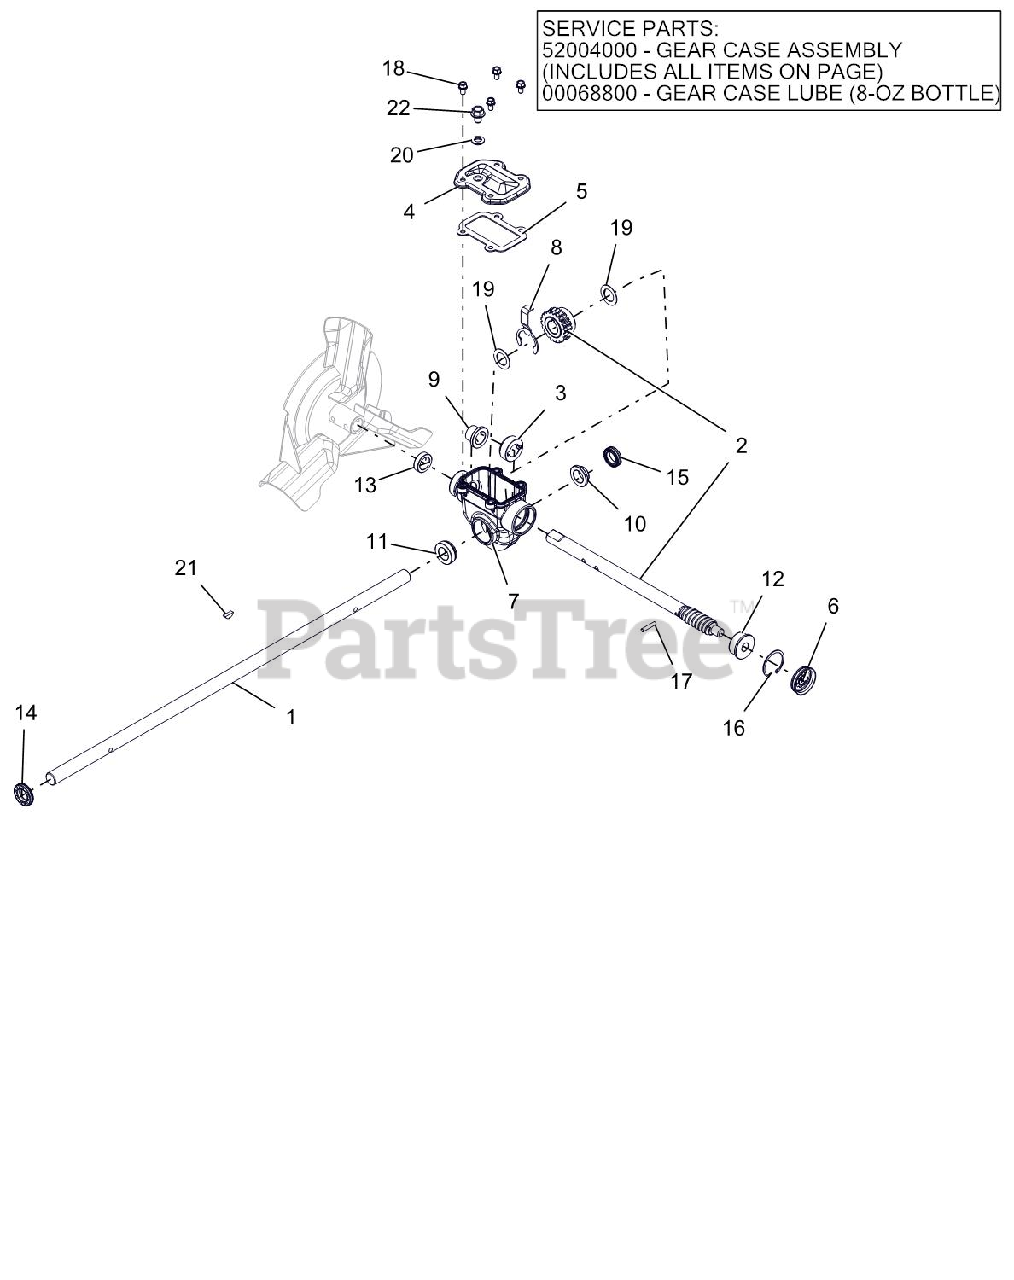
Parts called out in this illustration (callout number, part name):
1	SHAFT, RAKE-28" (.750 DIA)
2	SHAFT AND WORM GEAR ASSEMBLY
3	THRUST COLLAR, .75" ID SLIPFIT
4	COVER, TOP - COMPACT
5	GASKET, TOP - COMPACT GEARCASE
6	COVER, GEAR CASE 1.50"
7	GEARCASE, COMPACT ALUMINUM
8	BUSHING RETAINER, COMPACT
9	BSHG-FLG .755X.878X.75X1.25
10	BSHG-FLG .755X.878X.424X1.25
11	BSHG-FLG COMPACT, RIGHT
12	BSHG-FLG .503X1.303X.62X1.465
13	SEAL-OIL .748X1.125X.312 TB2-H
14	SEAL-OIL .748X1.300X.250 TBC29
15	SEAL-OIL .748X1.125X.312 TBC29
16	RG-RTNG-INT 1.500X.050
17	PIN-STR .188X1.00 6150
18	BOLT, SEMS .25-20X.50 GR5 YWZC
19	WSHR-FL-STL .760X1.225X.032 YZ
20	WSHR-BND-SEAL .38X.75X.11 GALV
21	KEY-WDRF .19X.63 HRD #61
22	@SCR-ROLOK .38-16X.50 HWH YWZC
23	GEAR CASE, 28" ALUM SM TOP-LD
24	ARIENS L3 LUBE, 8 OZ BOTTLE
